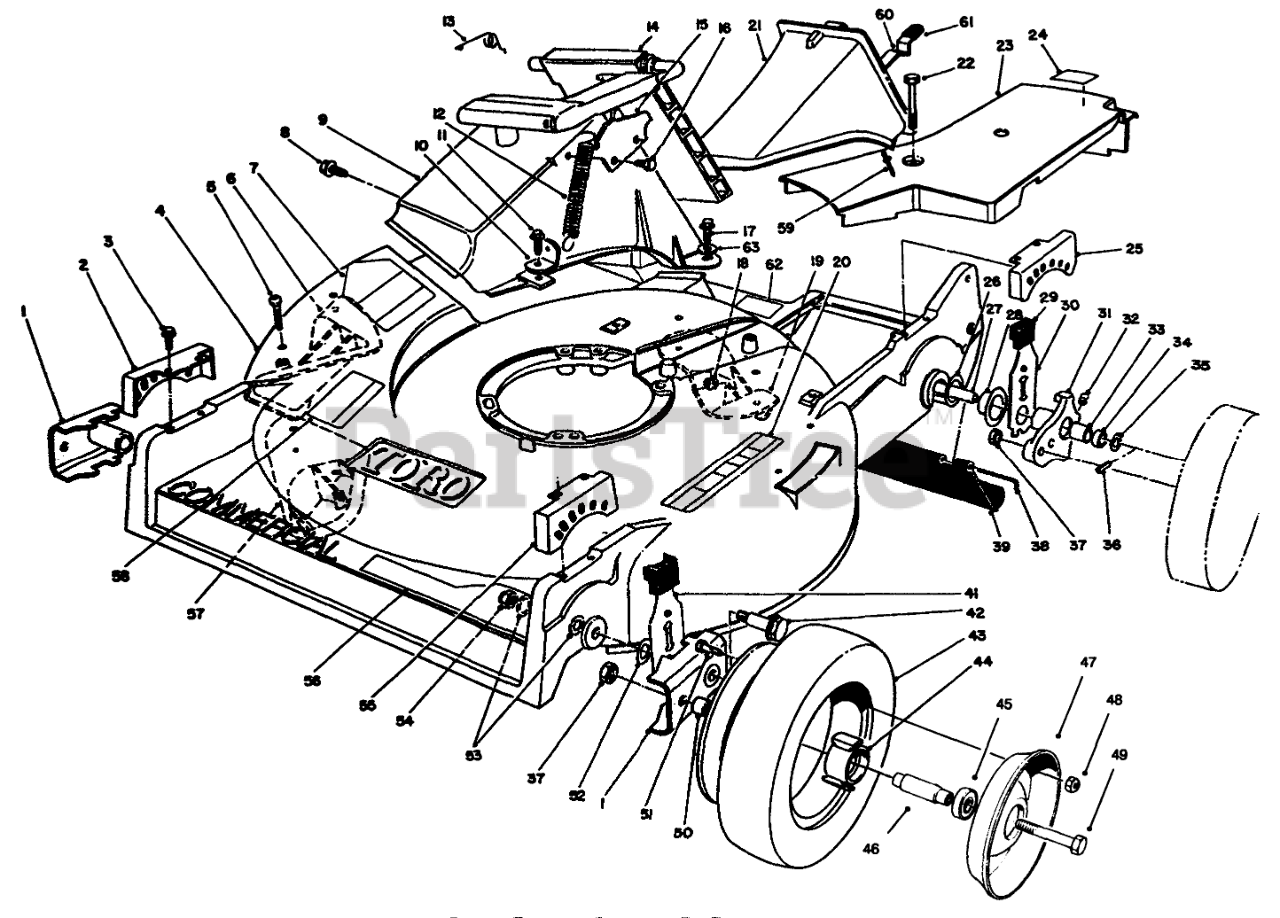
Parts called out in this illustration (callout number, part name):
1	ARM-PIVOT, FRONT
2	QUADRANT-FRONT, RH
3	SCREW-HWHTF
4	Housing (Incl. Ref.# 5-7, 19, 20, 57, 58 & 62)
5	SCREW-PPH
6	KICKER-RH
7	DECAL-DANGER
8	SCREW AND WASHER ASM
9	DISCHARGE TUNNEL
10	BRACKET-SPRING
11	SCREW-HWH
12	SPRING-DOOR
13	RETAINER-DOOR
14	DOOR ASSEMBLY
15	DOOR LATCH PLATE
16	SCREW-PLASTITE
17	SCREW-HH
18	NUT-LOCK, NI
19	KICKER-REAR
20	DECAL-INSTRUCTION, SAFETY
21	DISCHARGE PLUG ASM
22	SCREW-HHFTF
23	COVER-BELT
24	LABEL-GREASE, HP
25	QUADRANT-REAR, LH
26	WASHER
27	SHAFT-AXLE, REAR
28	CAP-END
29	KNOB-ARM
30	REAR SPRING ARM ASM
31	Arm-Pivot (Incl. Ref. #32-34)
32	FITTING-GREASE
33	BUSHING
34	BUSHING
35	WASHER-PLAIN
36	PIN-SPIROL
37	NUT-LOCK, CONE
38	ROD-SHIELD
39	SHIELD-TRAILING
41	FRONT SPRING ARM ASM
42	BOLT-WHEEL
44	HUB-BEARING
45	BEARING-WHEEL
46	SPACER-BEARING
47	Wheel-Half
48	NUT-LOCK, NI
49	SCREW-HH
50	SPACER-WHEEL
51	SCREW-HH
52	WASHER-THRUST
53	WASHER
54	NUT-LOCK
55	QUADRANT-FRONT, LH
56	DECAL - RECYCLER
57	KICKER-FRONT
58	DECAL - DANGER, COVERS
59	RIVET-HEAD, FLAT
60	LATCH-PLUG, DISCHARGE
61	GRIP-LATCH
62	DECAL-WARNING
63	WASHER-FLAT
